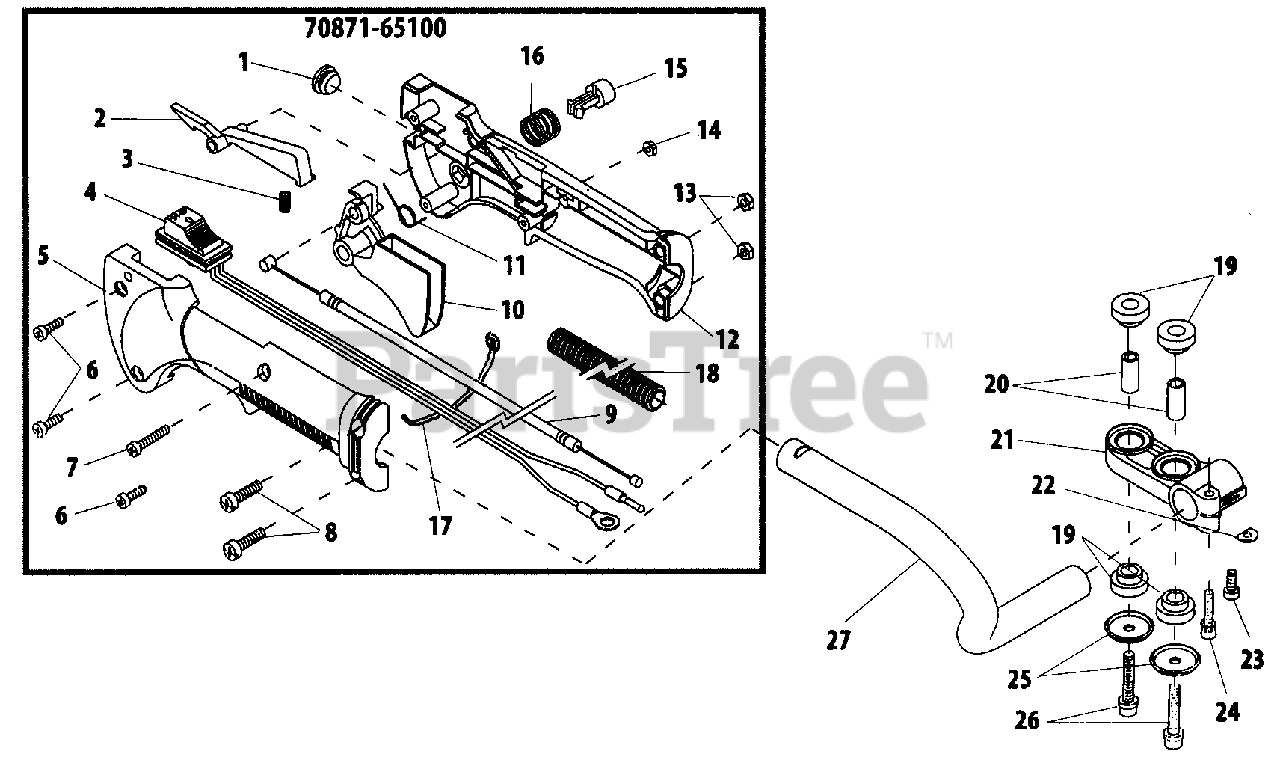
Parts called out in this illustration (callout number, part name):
1	PLUG, RUBBER
2	LOCKOUT, THROTTLE
3	SPRING, COMPRESSION
4	SWITCH ASSY
5	BODY - LEFT
6	SCREW - 4×16 -- TAPPING
7	SCREW M4×23
8	SCREW M5×20
9	CABLE, THROTTLE
10	TRIGGER, THROTTLE
11	SPRING, TORSION
12	GRIP BODY - RIGHT
13	NUT M5
14	NUT M4
15	BUTTON, THROTTLE LOCK
16	SPRING, COMPRESSION
17	STRAP, TIE
18	TUBE, PROTECTIVE - CORRUGATED
19	CUSHION
20	COLLAR 6
21	HANDLE STAY
22	D-WASHER
23	BOLT 5×12
24	BOLT M5×25
25	WASHER 6
26	BOLT M6×35
27	HANDLE, REAR
70871-65100	THROTTLE LEVER ASSY
